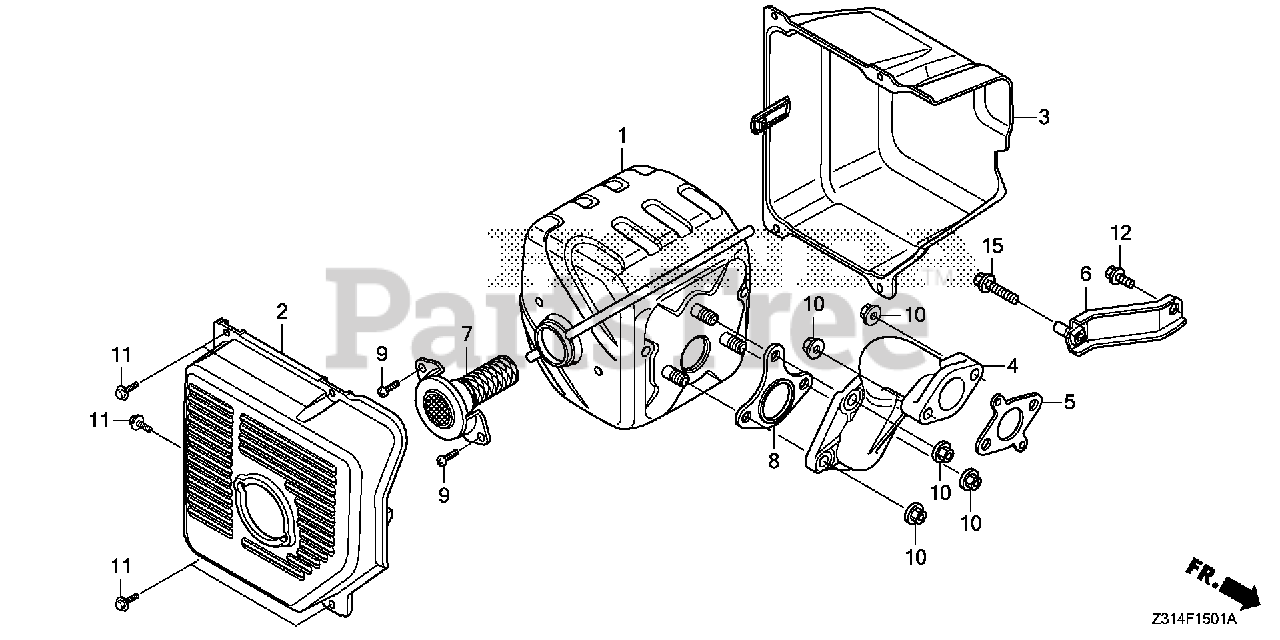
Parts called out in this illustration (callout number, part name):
2	PROTECTOR, MUFFLER (OUTER) *NH105* (MAT BLACK)
3	PROTECTOR, MUFFLER (INNER) *NH105* (MAT BLACK)
5	GASKET, EX. PIPE
6	STAY, MUFFLER
7	ARRESTER, SPARK
8	GASKET, MUFFLER (NIPPON LEAKLESS)
9	SCREW, TAPPING (5X8)
10	NUT, FLANGE (8MM)
11	BOLT, FLANGE (6X10)
12	BOLT, FLANGE (8X16) Use from Engine SN 1000016.
15	BOLT, FLANGE (8X22) Use from Engine SN 1609607.
